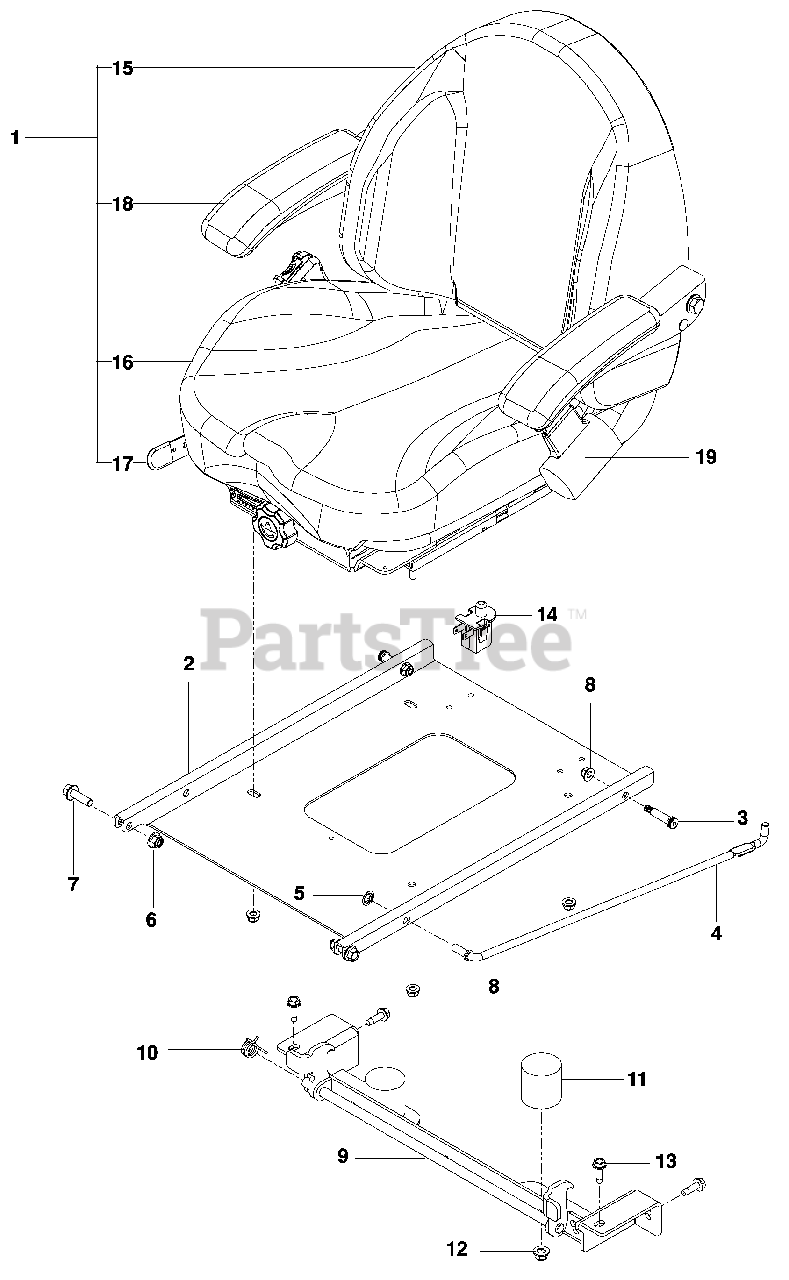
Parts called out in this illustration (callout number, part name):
1	SEAT ASSY
3	BOLT 3/8 x 1¼ 5/16-18 SHLDR
4	ROD, SEAT
5	RETAINER NUT 3/8
6	NUT 3/8-16 HEX FLG NYLOC
7	SCREW 3/8-16 x 1¼ HEX FLG
8	NUT 5/16-18 HEX FLG NYLOC
9	LATCH, SEAT
10	SPRING, TORSION
11	BUMPER, RUBBER
12	NUT 3/8-16 HEX FLG NYLOC
13	BOLT 5/16-18 x 1 THD FRM
14	SWITCH, SEAT
15	COVER, BACK
16	COVER KIT, CUSHION
18	ARMREST, LT
20	SEAT BELT
